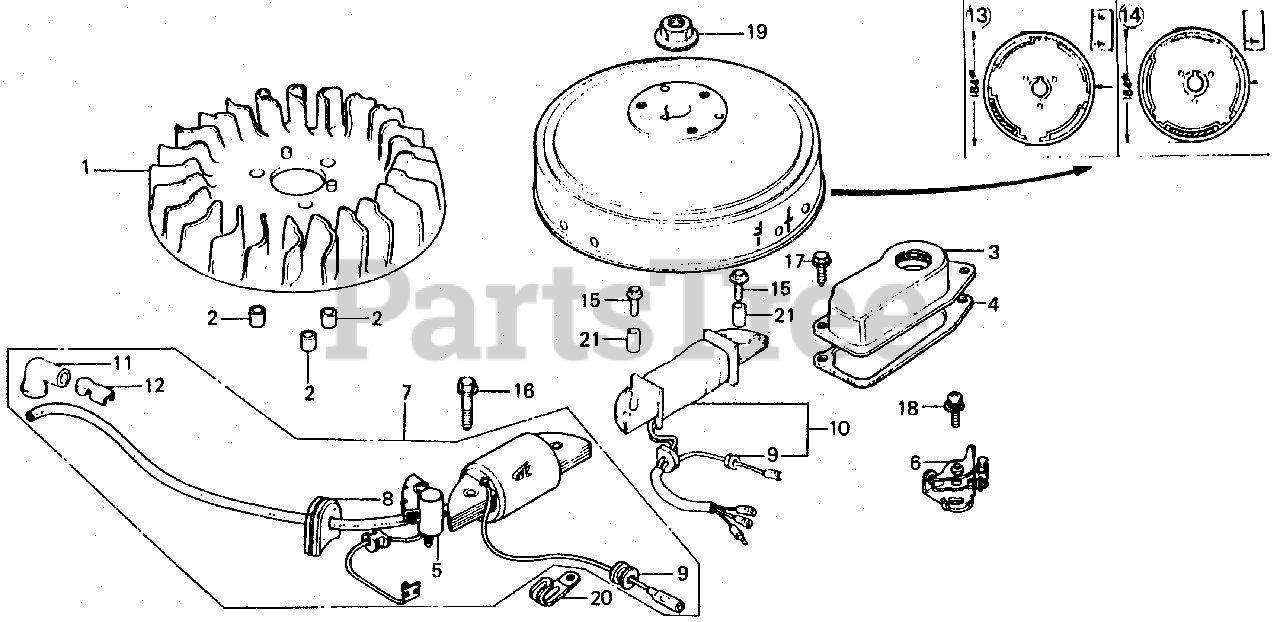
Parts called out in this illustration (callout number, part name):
1	FAN, COOLING
2	COLLAR, FAN
9	GROMMET, PRIMARY WIRE
10	COIL ASSY., EXCITER
10	COIL ASSY., EXCITER (NOT AVAILABLE)
14	FLYWHEEL (C.D.I.)
15	BOLT, FLANGE (6X28)
19	NUT, SPECIAL (14MM)
20	CLIP, CABLE
21	PIN A, DOWEL (8X14)
